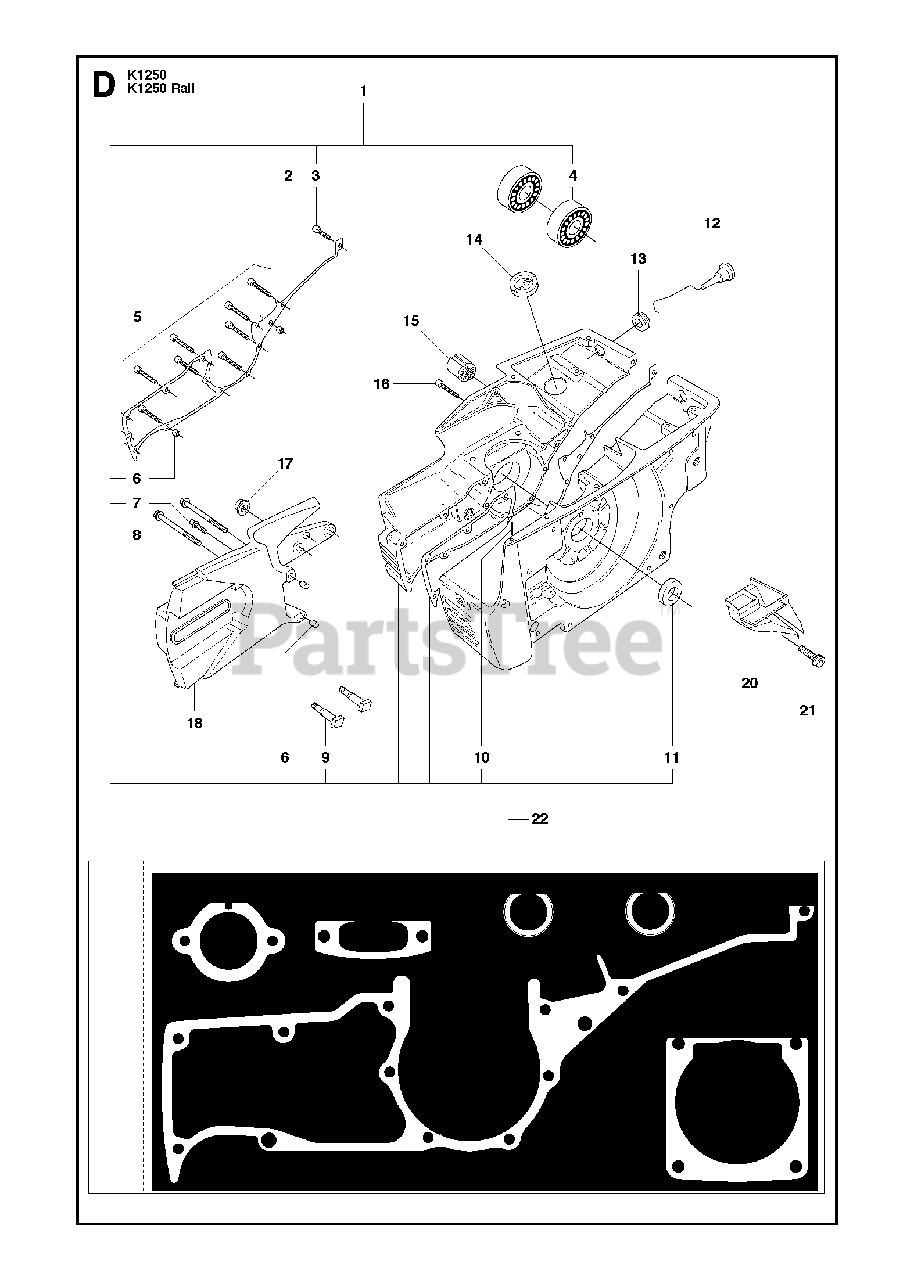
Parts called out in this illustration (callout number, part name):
1	CRANKCASEIncl. 2-11
2	CRANKCASEGasket kit 22
3	SCREW IHSCM
4	BALL BEARING
5	SCREW IHSCM
6	GUIDE BUSHING
7	SCREW IHSCFM
8	SCREW IHSCFM
11	SEALING RINGGasket kit 22
12	CHOKE CONTROL
15	ANTIVIBRATION ELEMENT
18	CUTTER ARM
21	SCREW IHSCFM
22	GASKET KIT
23	GASKET
24	GASKET
